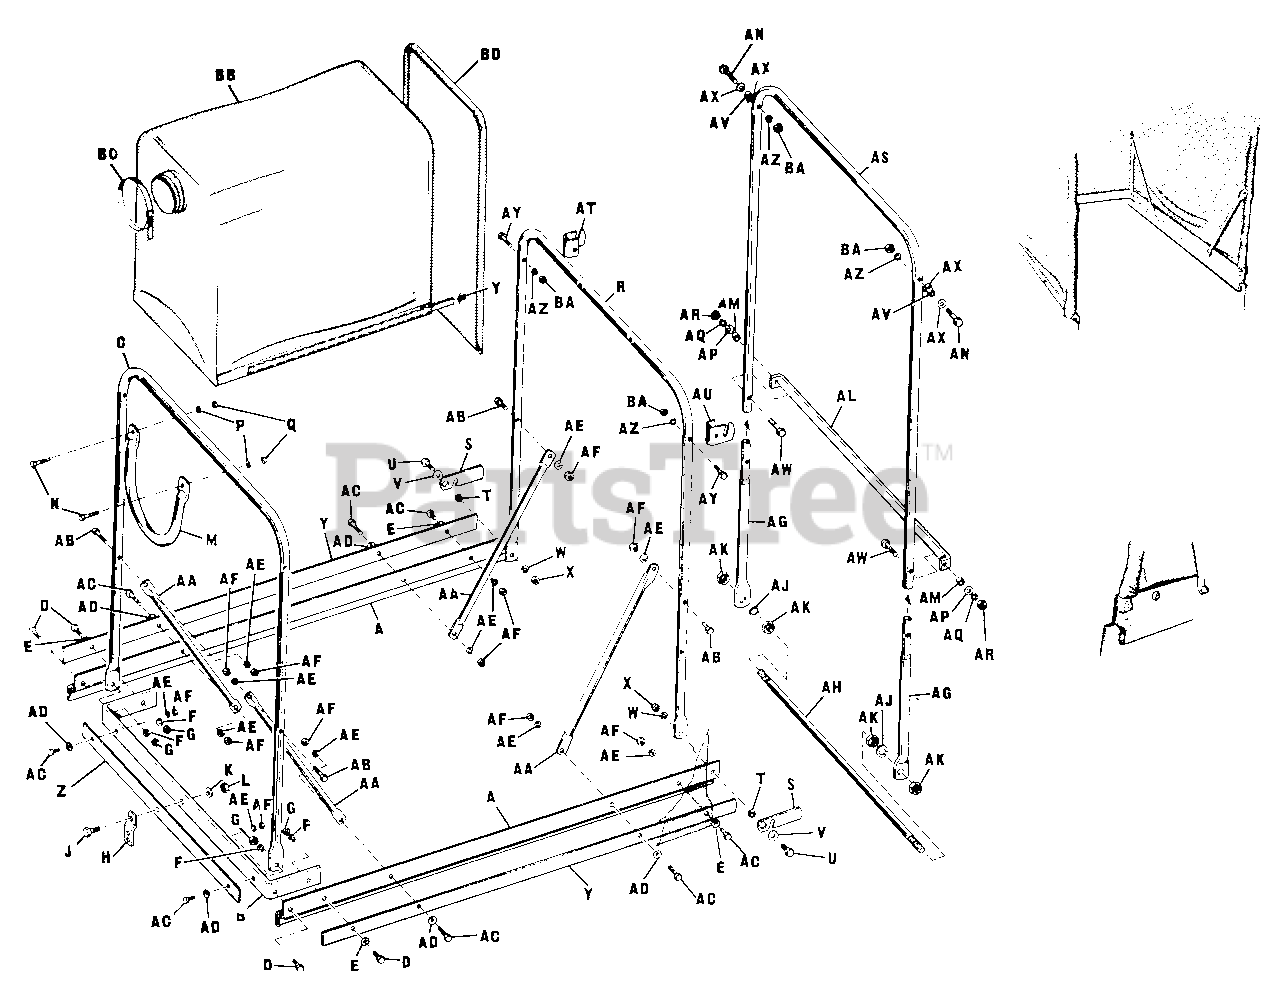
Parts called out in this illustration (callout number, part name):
A	"Z" Bar, Side
B	Front Bar
C	Front and Rear Upright
D	Hex Capscrew, 5/16"-18 x 1" lg.
E	Plain Washer, 5/16"
F	Lock Washer, 5/16"
G	Hex Nut, Full, 5/16"-18
J	Hex Capscrew, 3/8" x 16 x 1" lg.
K	Plain Washer, 3/8"
L	Hex Lock Nut, Full, 3/8"-16
M	Hose Support
N	Hex Capscrew, 1/4"-20 x 1-1/4 lg.
P	Lock Washer, 1/4"
Q	Hex Nut, Full, 1/4"-20
R	Front and Rear Upright
S	Rear Door Latch
U	Hex Capscrew, 5/16"-18 x 7/8" lg.
V	Plain Washer, 5/16"
W	Lock Washer, 5/16"
X	Hex Nut, Full, 5/16"-18
Y	Hold Down Strip, Side
Z	Hold Down Strip, Front
AA	Cross Brace Tube
AB	Hex Capscrew, 1/4"-20 x 1-1/4" lg.
AC	Hex Capscrew, 1/4"-20 x 3/4" lg.
AD	Plain Washer, 1/4"
AE	Lock Washer, 1/4"
AF	Hex Nut, Full, 1/4"-20
AG	Tube, Rear Door
AH	Rod, Rear Door
AJ	Lock Washer, 1/2"
AK	Hex Nut, Full, 1/2"-13
AL	Bar, Rear Door
AN	Hex Capscrew, 1/4"-20 x 1-3/4" lg.
AP	Plain Washer, 1/4"
AQ	Lock Washer, 1/4"
AR	Hex Nut, Full, 1/4"-20
AS	Top Rear Door
AT	Catch, Door, R.H.
AU	Catch, Door, L.H.
AW	Hex Capscrew, 1/4"-20 x 1-3/4" lg.
AX	Plain Washer, 1/4"
AY	Hex Capscrew, 1/4"-20 x l-1/4" lg.
AZ	Lock Washer, 1/4"
BA	Hex Nut, Full, 1/4"-20
BC	Hose Strap
